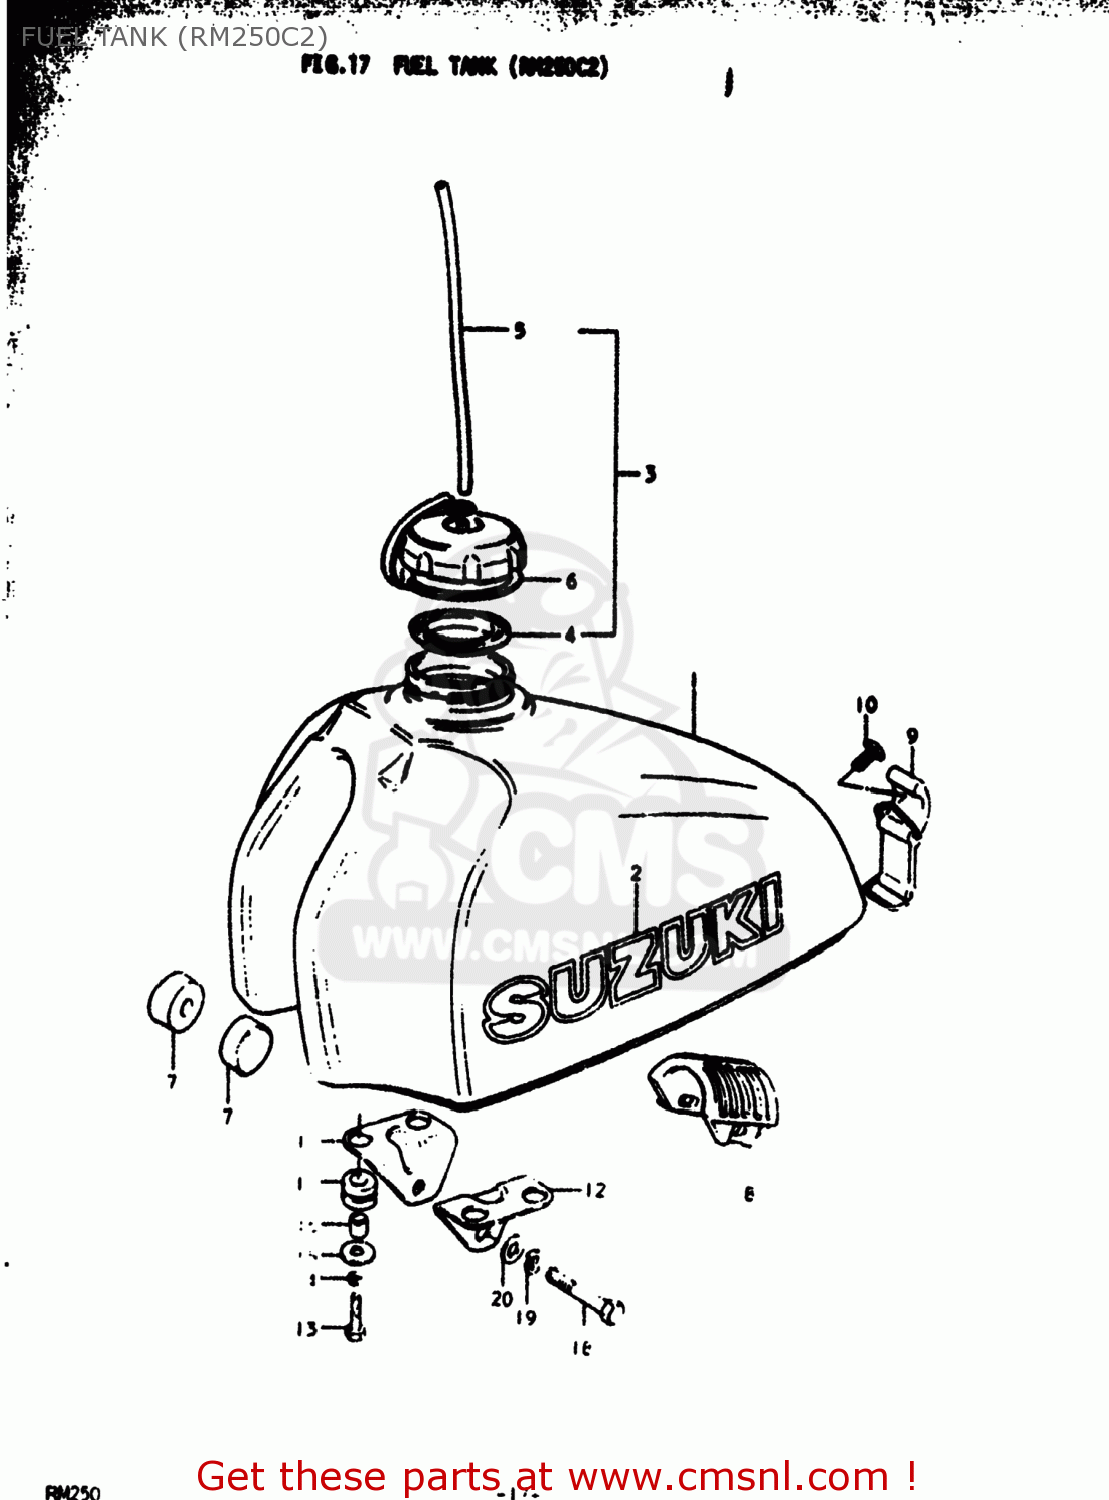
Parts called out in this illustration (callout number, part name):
1	TANK ASSEMBLY,FUEL
2	EMBLEM(BLACK)
3	CAP ASSY,FUEL TANK
4	GASKET,FUEL TANK CAP (NAS)
5	HOSE
6	BAND,FUEL TANK CAP
7	CUSHION
8	CUSHION,FUEL TANK
9	BAND
10	SCREW(6X18)
11	BRACKET,FUEL TANK
12	BRACKET,FUEL TANK
13	BOLT
14	LOCK WASHER
15	WASHER (6.5X20X1.2)
16	SPACER (6.8X10X10)
17	CUSHION
18	BOLT
19	LOCK WASHER
20	WASHER
